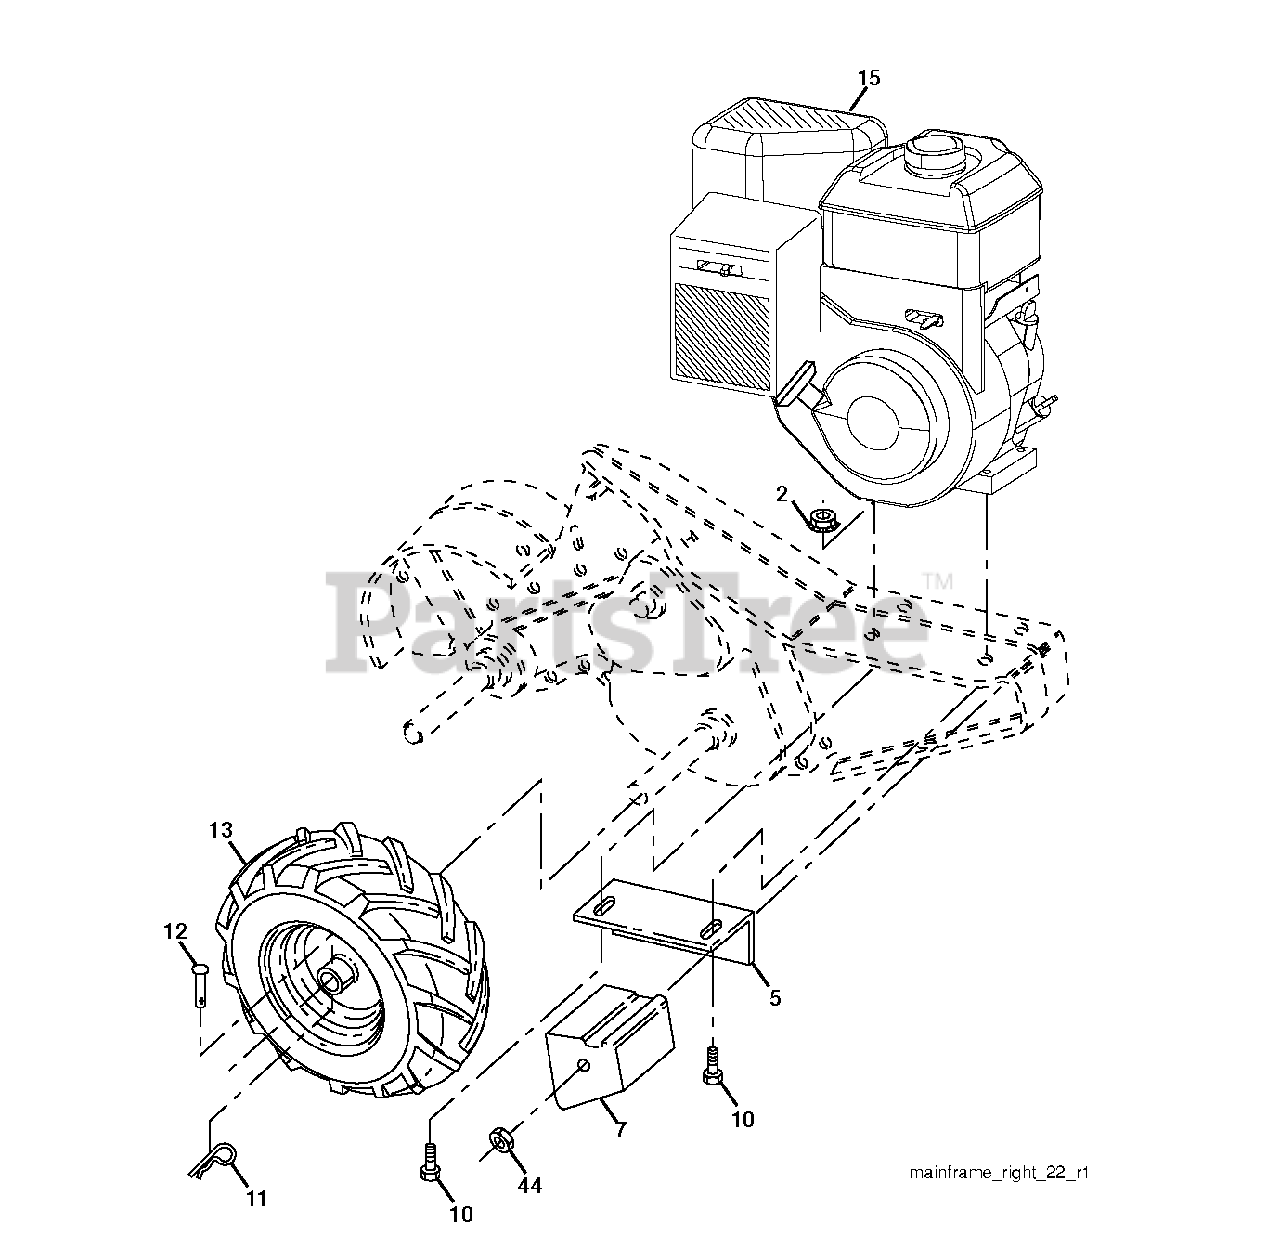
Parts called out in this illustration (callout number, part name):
2	LOCKNUT-FLANGE 5/16-18
5	BRACKET RH CRT
7	COUNTERWEIGHT, RH
10	BOLT
11	RETAINER M
12	RIVET,DRILLED
13	VALVE STEM LT
